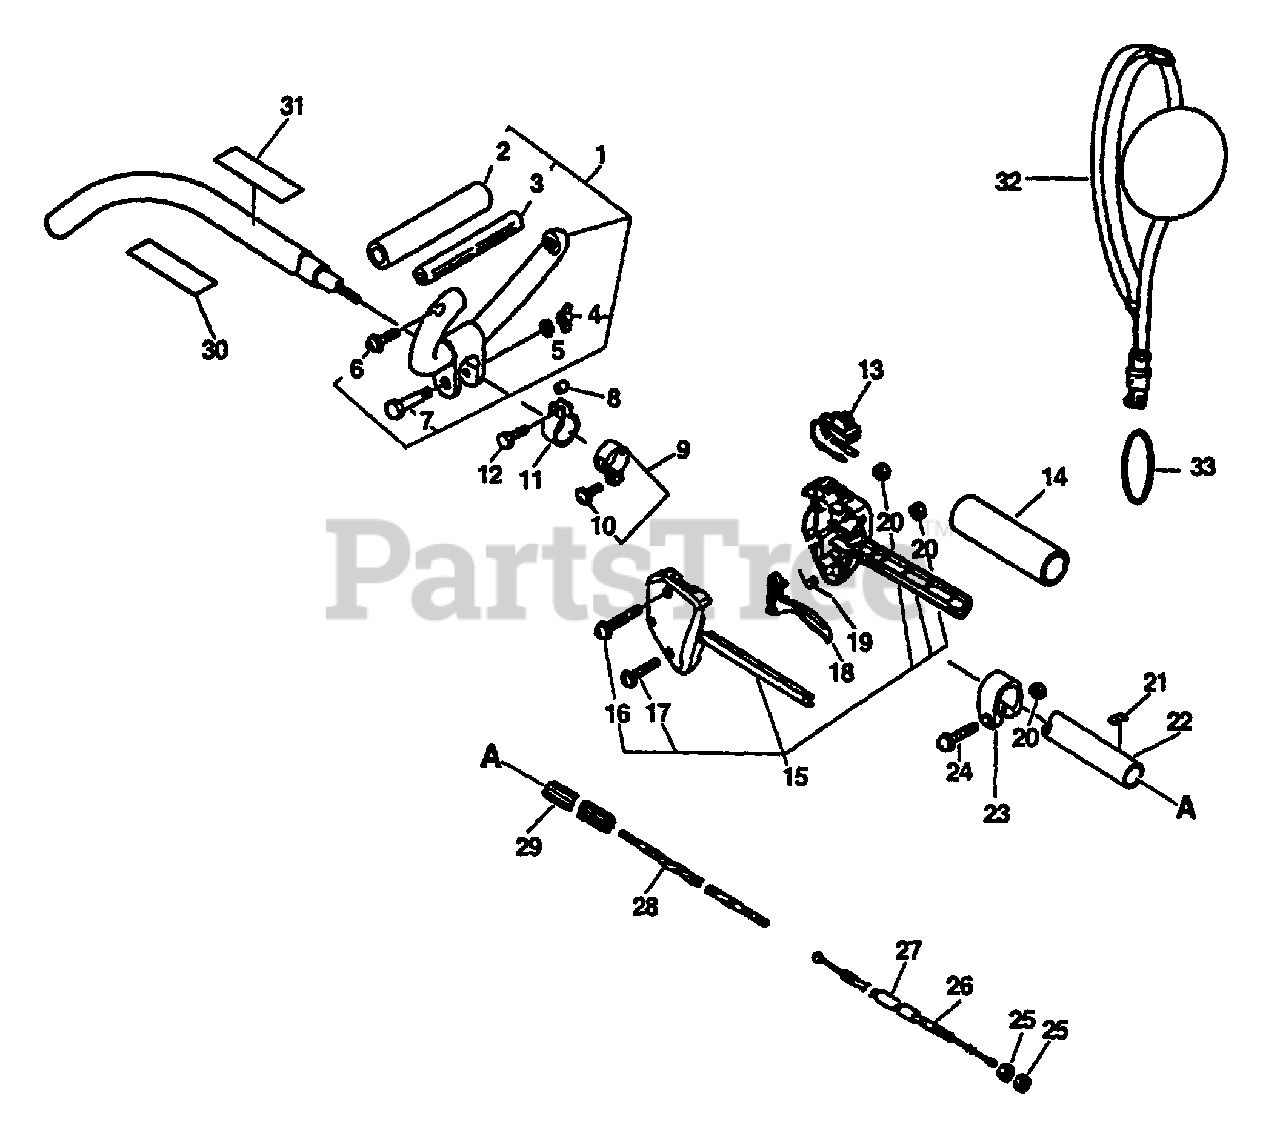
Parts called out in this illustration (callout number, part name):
1	LOOP HANDLE ASSY
2	GRIP, HANDLE
4	WINGNUT - 6
5	WASHER - 6
6	SCREW - 5X30
7	BOLT - 6X40
9	CLAMP KIT
10	SCREW - 5X14
12	BOLT - 5X18
13	IGNITION SWITCH ASSY
14	GRIP, HANDLE - REAR
15	CONTROL HANDLE ASSY
16	SCREW - 5X35
17	SCREW - 5X25
18	TRIGGER, THROTTLE
19	SPRING, TRIGGER
21	LABEL - ALIGNMENT
22	MAIN PIPE ASSY
24	SCREW - 5X28
26	CABLE, THROTTLE
27	TUBE - VINYL
28	DRIVESHAFT - FLEXIBLE
29	LINER - FLEXIBLE
30	LABEL - CAUTION
31	LABEL - CAUTION
32	SHOULDER STRAP ASSY
